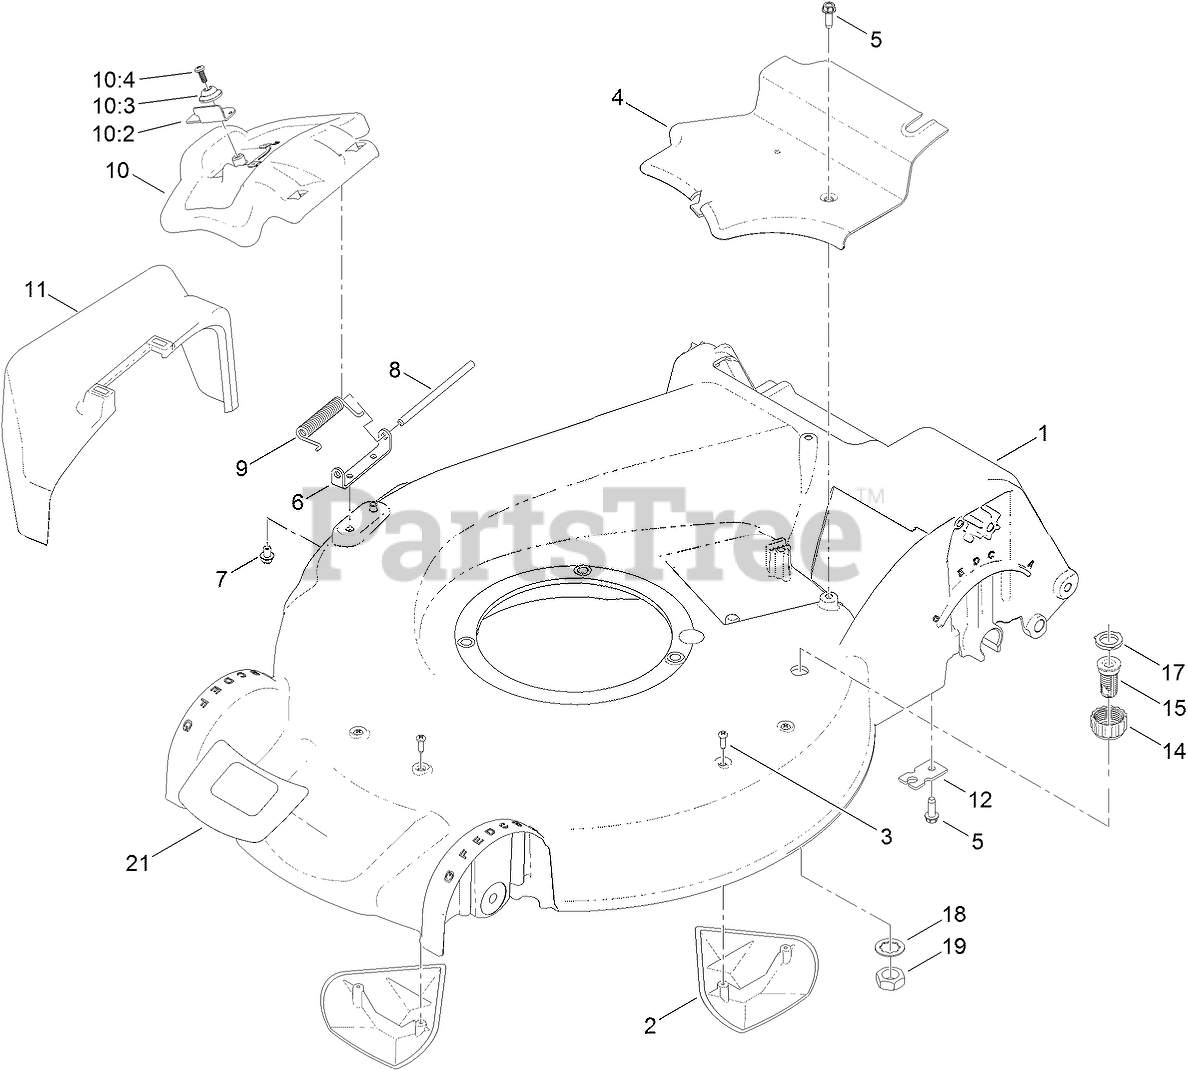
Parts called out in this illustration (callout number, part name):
1	HOUSING ASM
2	KICKER-HOUSING
3	SCREW-PPH
4	COVER-BELT
5	SCREW-HWHTF
6	BRACKET-COVER
7	SCREW-HWH
8	ROD-COVER
9	SPRING-TORSION
10	DISCHARGE DOOR ASM
10:2	LATCH-DOOR
10:3	CAP-DOOR
10:4	SCREW-PLASTITE
11	CHUTE-DISCHARGE, SIDE
12	BRACKET-CABLE, TRACTION
14	COUPLING-HOSE, WASHOUT PORT
15	PORT-WASHOUT
17	WASHER-SEAL, WASHOUT PORT
18	WASHER-TOOTH, INTERNAL
19	NUT-JAM
21	DECAL-DECK
